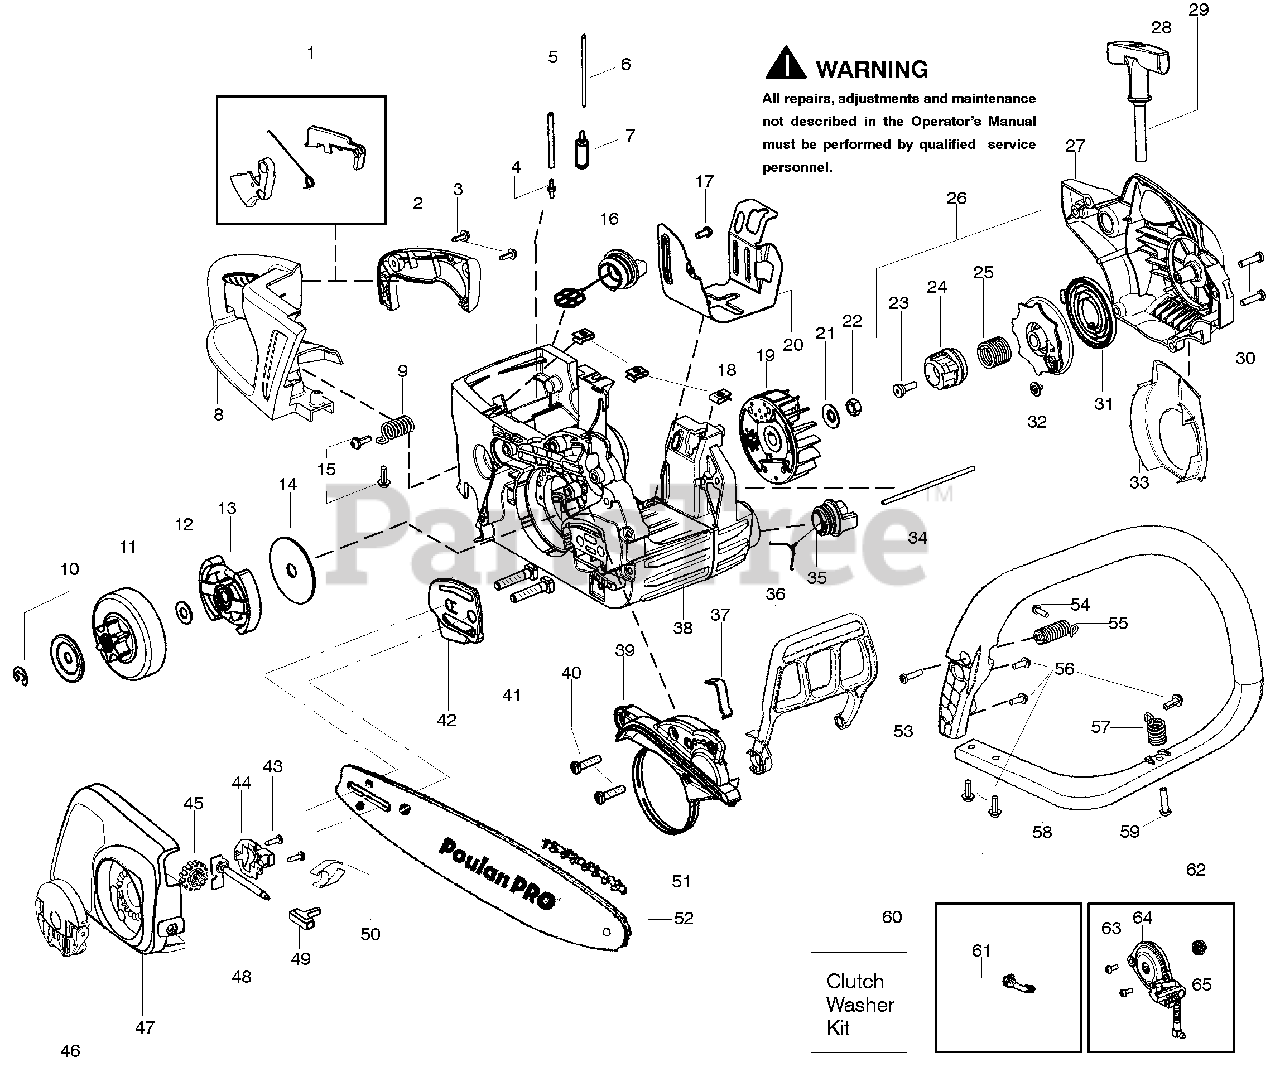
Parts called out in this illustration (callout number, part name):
1	Kit-Trigger/Lockout
2	Cover-Handle
4	Fitting-Fuel line
5	Kit-Fuel Line (Large)
6	Kit-Fuel Line (Small)
7	Assy-Fuel Pick Up
8	Handle-Rear
9	Spring-Rear Isolator
10	Kit-Clutch Washer
11	Assy-Clutch Drum 3/8"
12	Kit-Clutch Washer
13	Assy-Clutch
14	Washer-Large Clutch
16	Assy-Fuel Cap w/ret
18	Nut-"U" type speed
19	Assy-Flywheel
20	Shield-Heat
21	Washer-Flywheel
22	Nut-Flywheel
23	Screw-Shoulder
24	Starter Hub-EPS
25	Spring-EPS
26	Kit- EPS Starter Pulley
27	Housing-Fan
28	Handle-Starter
29	Kit-Rope
31	Spring-Starter
34	Assy-Oil Vent
35	Assy-Oil Cap w/ret.
36	Handguard
37	Spring-Handguard
38	Assy-Chassis
39	Kit-Chainbrake
41	Bolt-Bar
42	Plate-Bar
44	Cover-Gearbox
45	Assy-Bar Adj. wheel
46	Assy-Knob
47	Clutch Cover
48	Assy-Adjust Screw
49	Pin-Bar Adjust
50	Clip-Spring
51	Accy-16" Chain
52	16" Bar
55	Assy-Rear Iso. Spring
57	Assy-Front Iso. Spring
58	Handle-Front
60	Kit-Clutch Washer
61	Assy-Oil Pick Up
62	Kit-Oil Pump
64	Assy-Oil Pump
65	Gear-Worm
